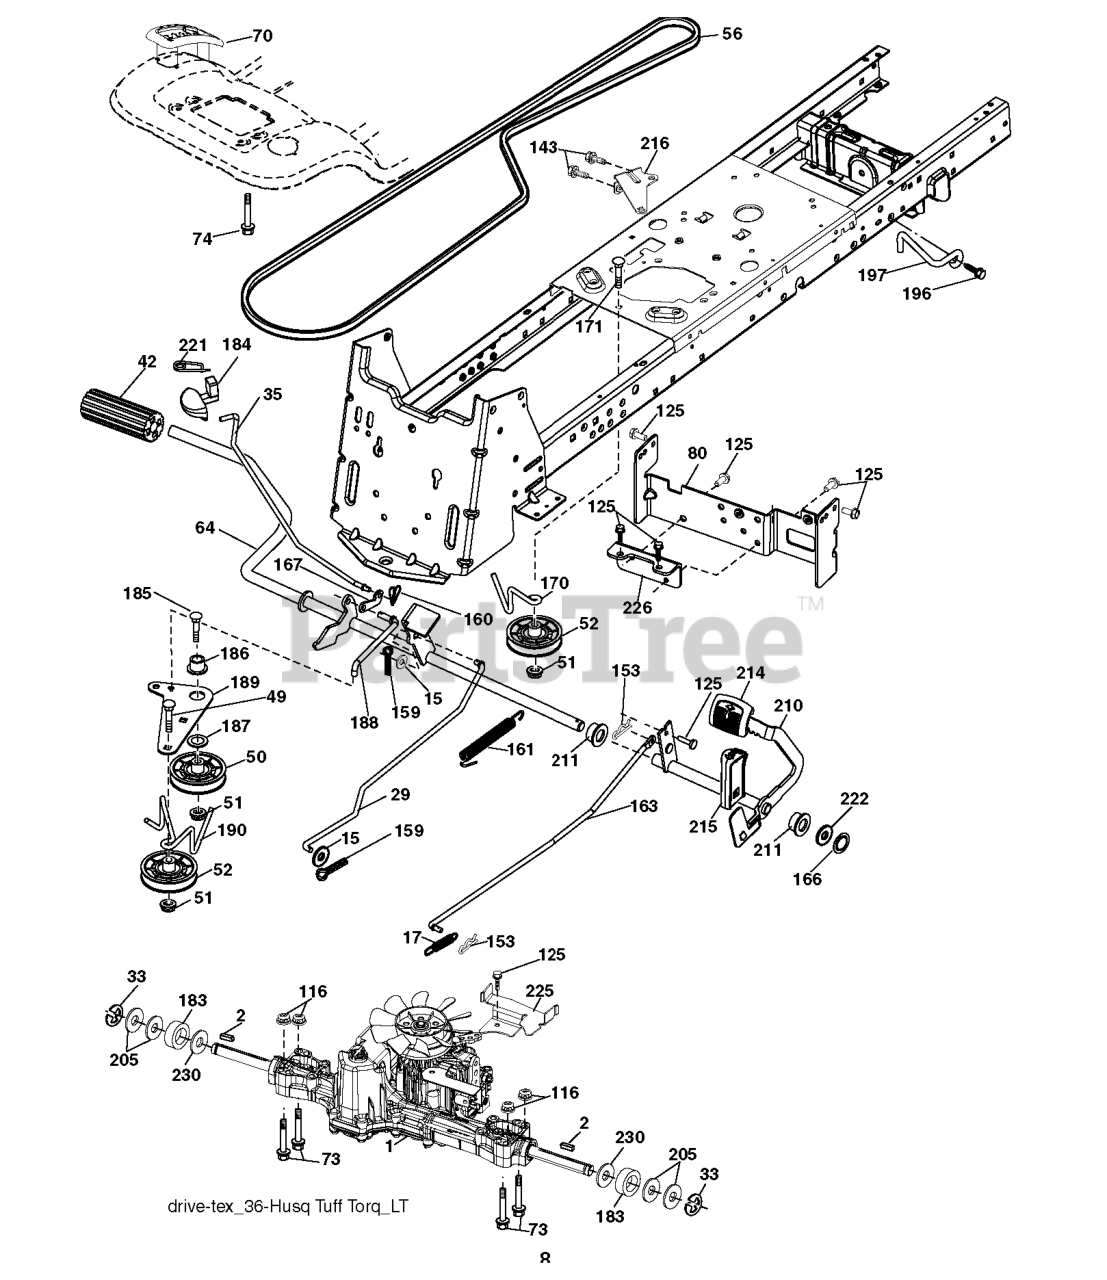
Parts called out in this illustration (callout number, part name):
2	SQUARE KEY
15	WASHER
17	SPRING.BRAKE.K46.GREEN
29	ROD.BRAKE.K46
35	ROD.CNTRL.PARK.PREDATOR.LT.TEX
42	PEDAL COVER T
50	IDLER.FLAT.910.OFFSET
51	NUT LOCK FLG 3/8-16 UNC
52	IDLER.V-GROOVE.910.OFFSET
56	V-BELT.MOWER.92.40.42/K46
64	SHAFT.ASM.PEDAL.BRK.CNTR
73	BOLT HEX 5/16-18 GR 5
80	STRAP.TORQUE.HG3000/K46
116	NUT LOCK HEX FLANGE 5/16-18
125	SCREW
143	Screw 5/16-18 x 1/2 Hex, Self Tapping 5/16-18 x 1/2
153	RETAINER M
159	COTTER PIN
160	RETAINER CLIP
161	SPRING.RETURN.CLUTCH.2006
163	ROD.CONTROL.PEDAL.K46
166	NUT.PUSH.625.2006
167	LATCH.BRAKE.SPRING
170	KEEPER.V-IDLER.CENTER.
183	SPACER AXLE
184	HANDLE PARKING BRAKE
186	SPACER.RETAINER
187	WASHER 12/32X2X10GA
188	RP.LINK.CLUTCH.GROUND.DRIVE
189	BELLCRANK.GROUND.DRIVE.TEX.
190	KEEPER.BELLCRANK.DRIVE
196	SCREW 3/8-16X1
197	LINK.CLUTCH.ANIT-ROTAT
210	ROCKER.ASM.PEDAL.CONTR
211	BEARING.NYLON
213	KNOB.CONTROL.CRUSIE.HU
214	PEDAL.FORWARD.TEX.GT.4
215	PEDAL.REVERSE.TEX.GT.4
216	BRACKET.PULLEY.IDLER.W/TEX
221	RETAINER.SPRING.CLIP.H
222	WASHER 21/32 X 1-1/4 X 10 GA.
225	KEEPER.BELT.TRANSAXLE.K46
226	BRACKET.MOUNT.TORQUE.K46.TLT
230	WASHER.HARDENED
